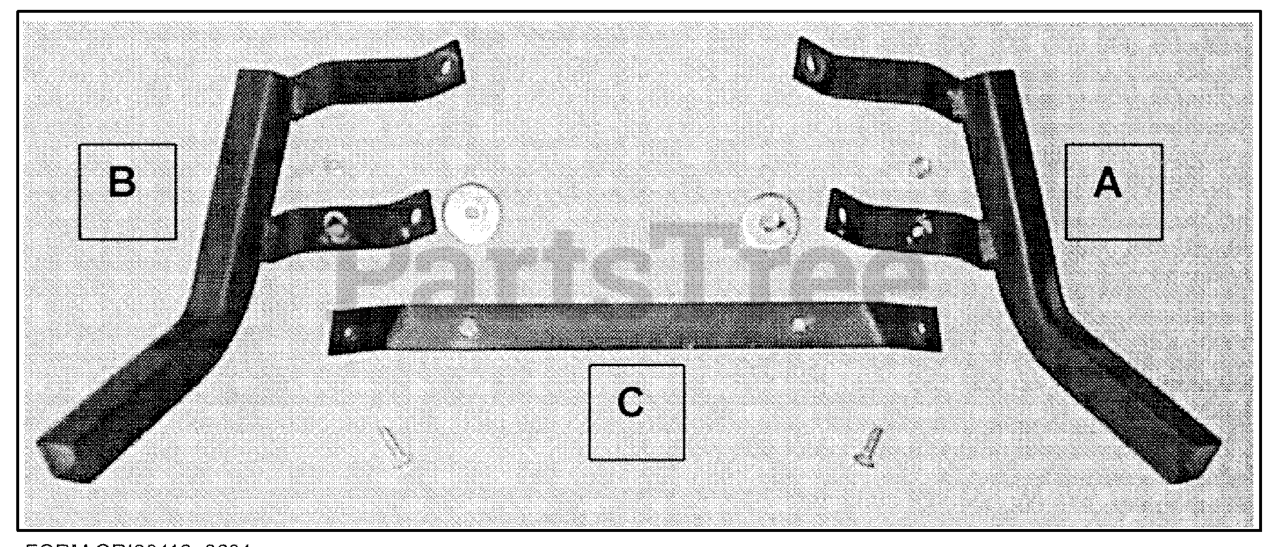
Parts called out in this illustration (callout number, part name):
A	RECEIVER, RH
B	RECEIVER, LH
C	CROSS BAR (Flat Fender LT Tractor ONLY)
